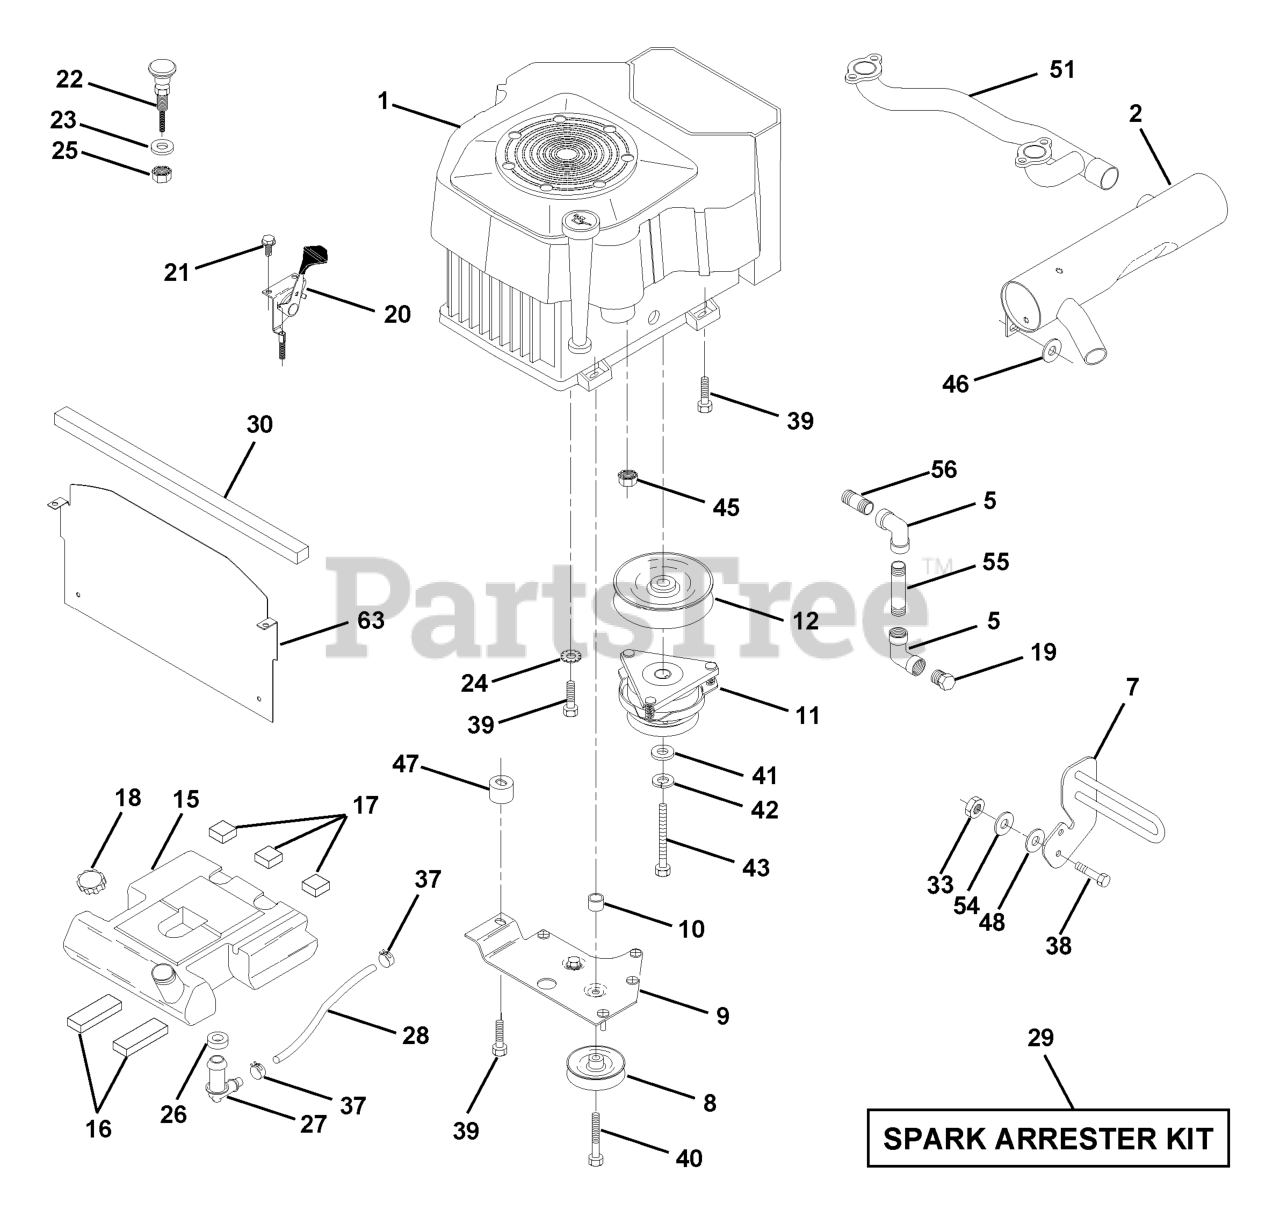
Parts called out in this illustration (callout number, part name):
2	MUFFLER VGT CYLINDER
5	ELBOW
7	MUFFLER ASSEMBLY GUARD
8	RP.IDLER GROOVED
9	KEEPER ASM. BELT ENGINE VGT 96
11	CLUTCH ELECTRIC
12	PULLEY ENG VGT ELECT CLUTCH
15	FUEL TANK 3.5G
16	PAD IDLER TI
17	PAD-SPACER LT
18	FUEL CAP
19	PLUG T
20	THROTTLE CONTROL
21	SCREW LT
22	CHOKE CONTROL
23	WASHER
24	LOCKWASHER
25	Nut Keps 3/8 - 24 UNF
26	BUSHING OUTLET T
27	STEM FUEL TANK
28	HOSE
29	SPARK ARRESTOR
30	FOAM-STRIP LT
33	NUT
37	HOSE CLAMP
38	BOLT
39	SCREW TT 3/8-16X2-1/4 UNC
40	Screw TT 3/8-16 x 4 UNC
42	LOCKWASHER
43	BOLT HEX
45	NUT FLANGE 1/4-20 STARTER NUT
46	WASHER
47	SPACER.ENGINE.CV22.ROUND.PM
48	Washer 13/32 x 1-1/4 x 7 Ga.
51	PIPE CROSSOVER
55	NIPPLE, PIPE 3/8NPT X 4-1/2
56	NIPPLE, PIPE 3/8 NPTX1.00
63	SHIELD, HEAT VGT YP/HUSQ
